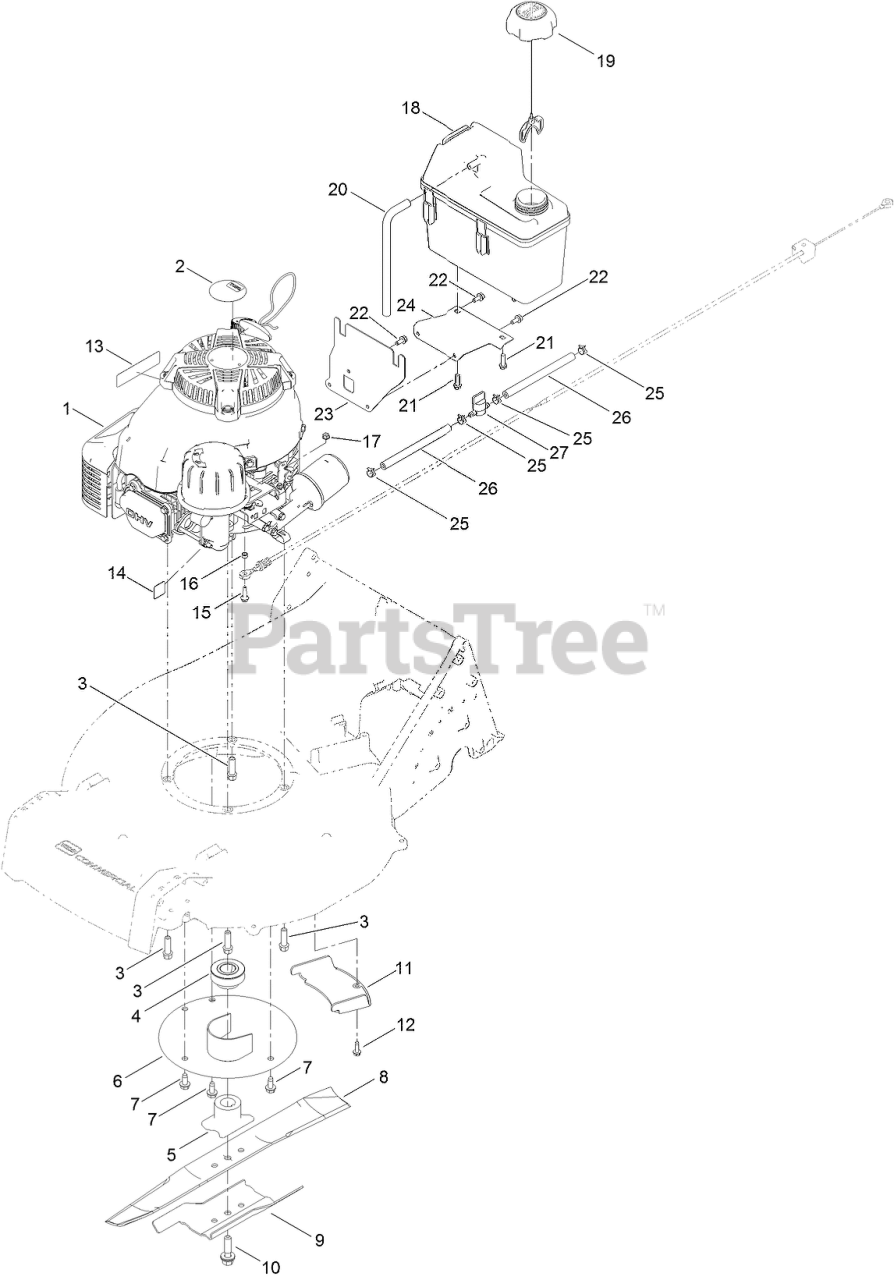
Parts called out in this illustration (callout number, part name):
3	SCREW-TAPTITE
4	PULLEY-DRIVER
5	DRIVER-BLADE
6	PROTECTOR-CRANKSHAFT
7	SCREW-HWHTF
8	BLADE-21IN, RECYCLING
9	ACCELERATOR-BLADE
10	BOLT-BLADE
11	COVER-BELT
12	SCREW-HWHTF
13	DECAL-ARRESTOR, SPARK
14	DECAL-PRIMER
15	SCREW-SHOULDER
16	SPACER
17	NUT-LOCK, FLANGE
18	TANK-FUEL
19	CAP-FUEL
20	HOSE-VENT, CANISTER
21	SCREW-HWH
22	SCREW-HWH
23	BRACKET-TANK, MOUNTING
24	BRACKET-TANK, SUPPORT
25	CLAMP-HOSE
26	HOSE-FUEL
27	VALVE-FUEL
